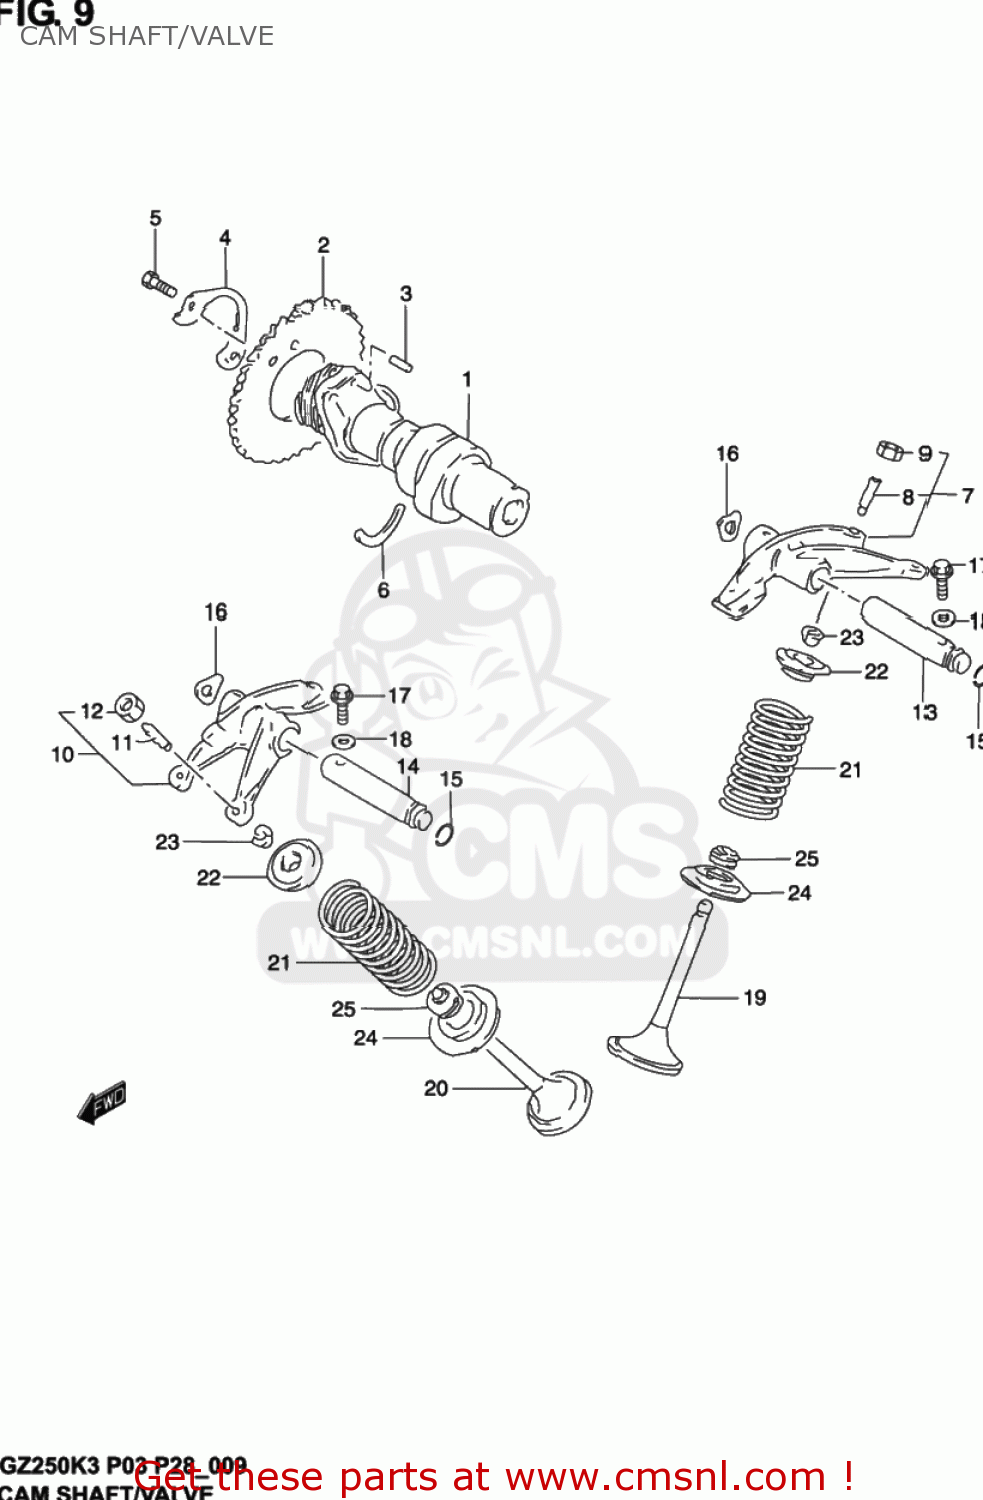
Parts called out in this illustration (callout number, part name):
1	CAMSHAFT
2	SPROCKET,CAMSHAFT(NT:42)
3	PIN
4	WASHER,CAM CHAIN SPROCKET
5	BOLT(6X12.5)
6	C RING
7	ARM,VALVE ROCKER INTAKE
8	SCREW,TAPPET ADJUSTING
9	NUT,TAPPET ADJUSTING
10	ARM,VALVE ROCKER EXHAUST
11	SCREW,TAPPET ADJUSTING
12	NUT,TAPPET ADJUSTING
13	SHAFT,VLV ROCKER ARM IN(L:91.5
14	SHAFT,VLV ROCKER ARM EXH(L:76)
15	O RING(D:1.9,ID:8.6)
16	WASHER
17	BOLT (GREEN)
18	GASKET(5.8X13X1.2) (NAS)
19	VALVE,INTAKE
20	VALVE,EXHAUST
21	SPRING,VALVE
22	RETAINER,VALVE SPRING
23	COTTER VALVE
24	SEAT,VALVE SPRING
25	SEAL,OIL(5.5X11X8.2)
